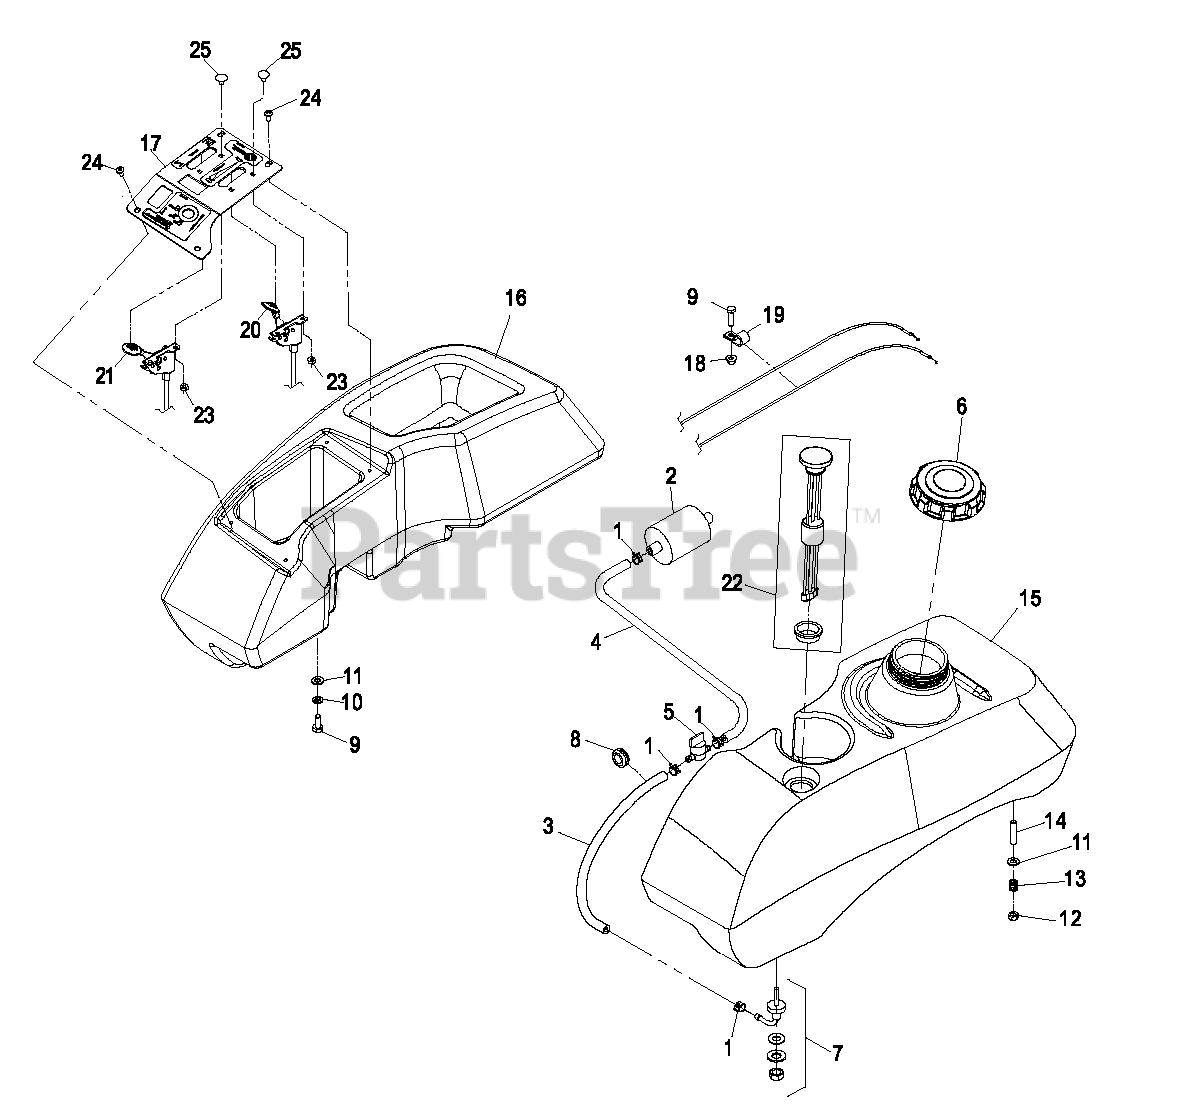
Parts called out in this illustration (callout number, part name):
2	Briggs & Stratton Part No. 493629 Fuel Filter
3	HOSE-FUEL
4	HOSE-FUEL
5	VALVE-FUEL
6	CAP-FUEL, GAS
7	FITTING-FUEL, BULKHEAD
7	O-RING,BULKHEAD FITTING
8	GROMMET
9	SCREW-HH
10	WASHER-LOCK
11	WASHER-PLAIN
12	NUT-LOCK, NI
13	SPRING-TANK, FUEL
14	STUD
15	KIT,FUEL TANK LH LCT
16	ASM, TANK RH LCT S.O.
17	PANEL,CONTROL W/DECALS
19	CLIP-LOOM
20	CONTROL,THROTTLE
21	CONTROL,CHOKE
23	NUT-LOCK, NI
24	SCREW-PPH
25	BOLT-CARR
